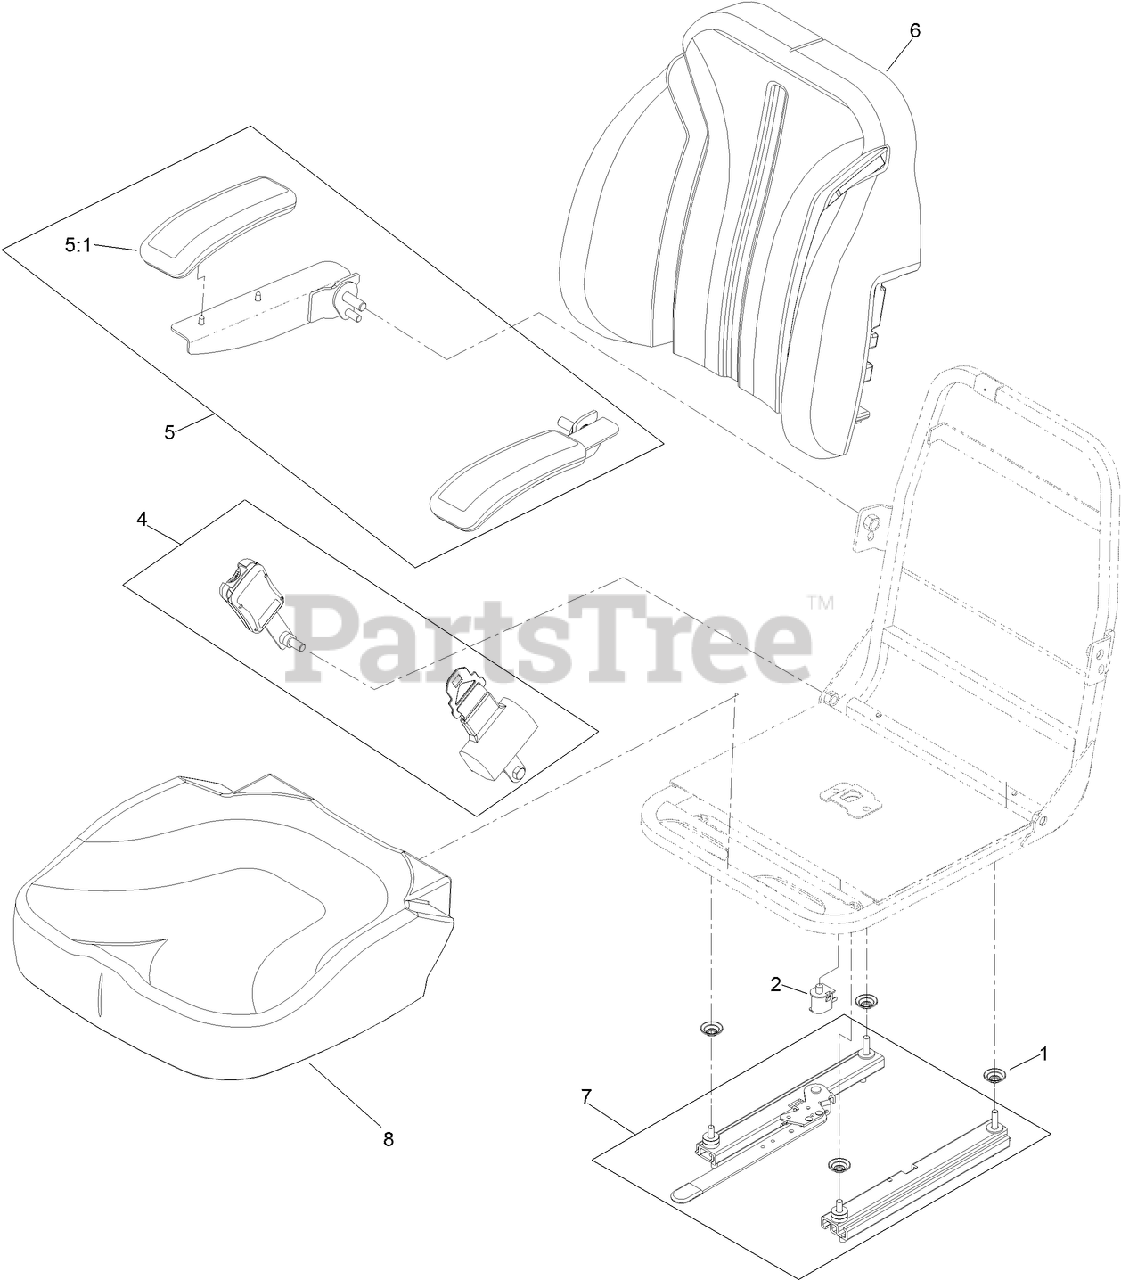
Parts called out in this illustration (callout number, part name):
1	SPACER-MOUNTING
2	SWITCH-BAIL
4	SEAT BELT KIT
5	ARMREST KIT
5:1	CUSHION-REST, ARM
6	COVER-BACK, SEAT
7	TRACK-SEAT
8	COVER-SEAT, BOTTOM
